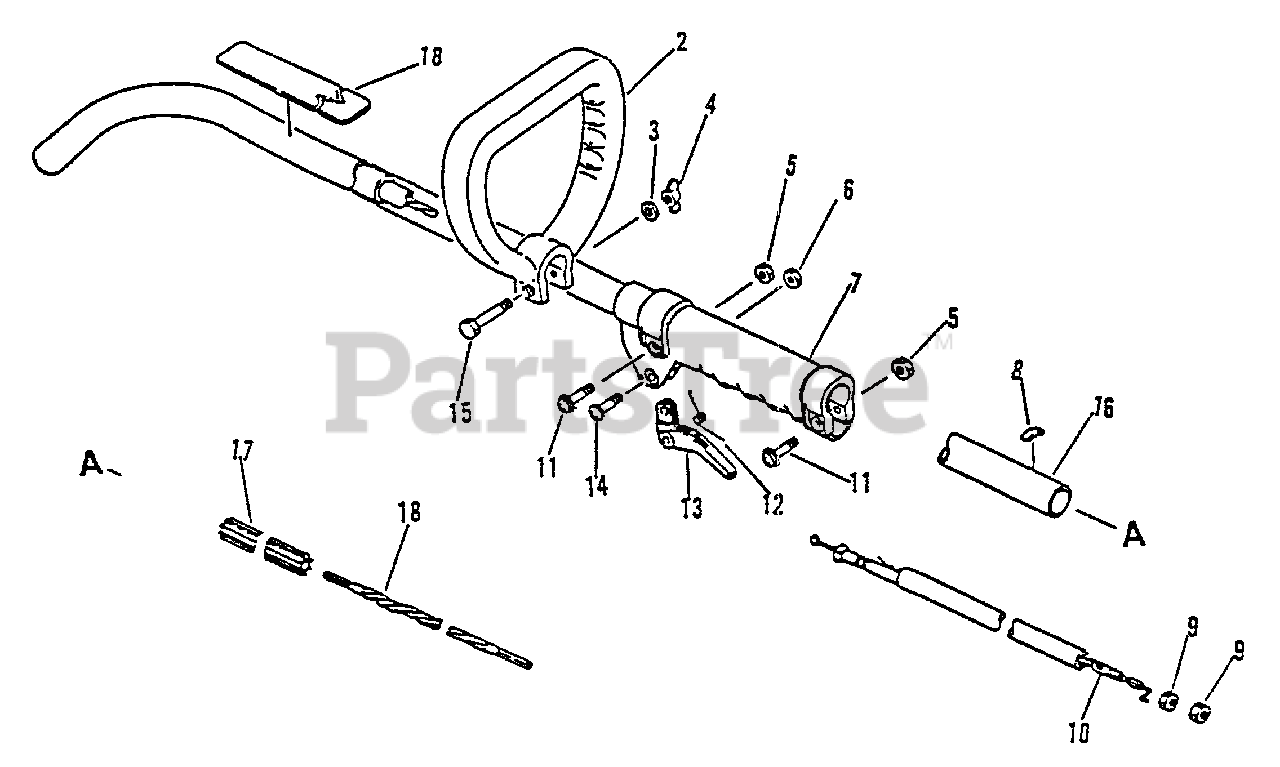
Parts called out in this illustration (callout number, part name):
1	MAIN PIPE ASSY
2	HANDLE - FRONT
3	WASHER - 6
4	WINGNUT - 6
6	LOCKNUT - 5
7	GRIP, HANDLE
8	LABEL - ALIGNMENT
10	CABLE, THROTTLE
11	SCREW - 5X25
12	SPRING, TRIGGER
13	TRIGGER, THROTTLE
14	SCREW - 5X30
15	BOLT - 6X40
16	DRIVESHAFT - FLEXIBLE
17	LINER - FLEXIBLE
18	LABEL - CAUTION
